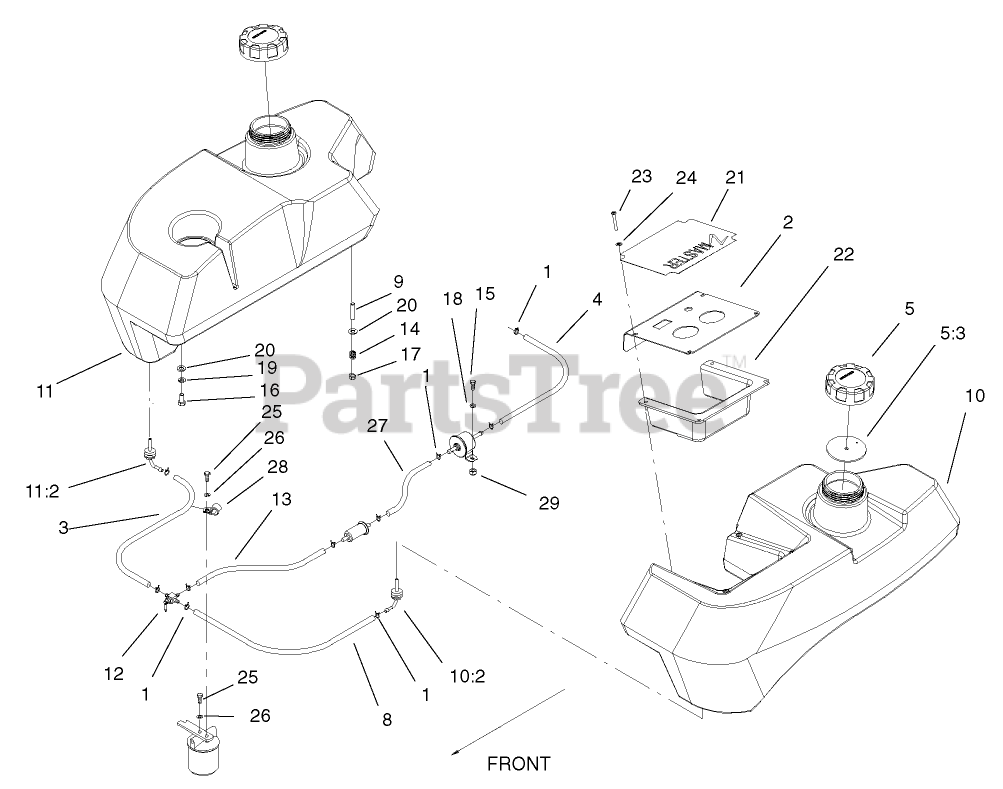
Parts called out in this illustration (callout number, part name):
2	PANEL-CONTROL
3	Hose-Fuel
4	Hose-Fuel
5	GAS CAP ASM
5:3	GASKET-CAP, GAS
8	HOSE-FUEL
10	ASM, Tank-Fuel LH
10:2	FITTING-FUEL, BULKHEAD
11	ASM, Tank-Fuel RH
11:2	FITTING-FUEL, BULKHEAD
12	VALVE-FUEL
13	HOSE-FUEL LINE
14	SPRING-TANK, FUEL
15	SCREW-HH
16	SCREW-HH
17	NUT-LOCK, NI
18	WASHER-FLAT
19	WASHER-LOCK
20	WASHER-PLAIN
21	DECAL-CONTROL PANEL
22	SHIELD-PANEL, CONTROL
24	WASHER-SPRING
25	SCREW-HH
26	WASHER-LOCK
27	HOSE-FUEL
28	CLIP-LOOM
29	NUT-HF
